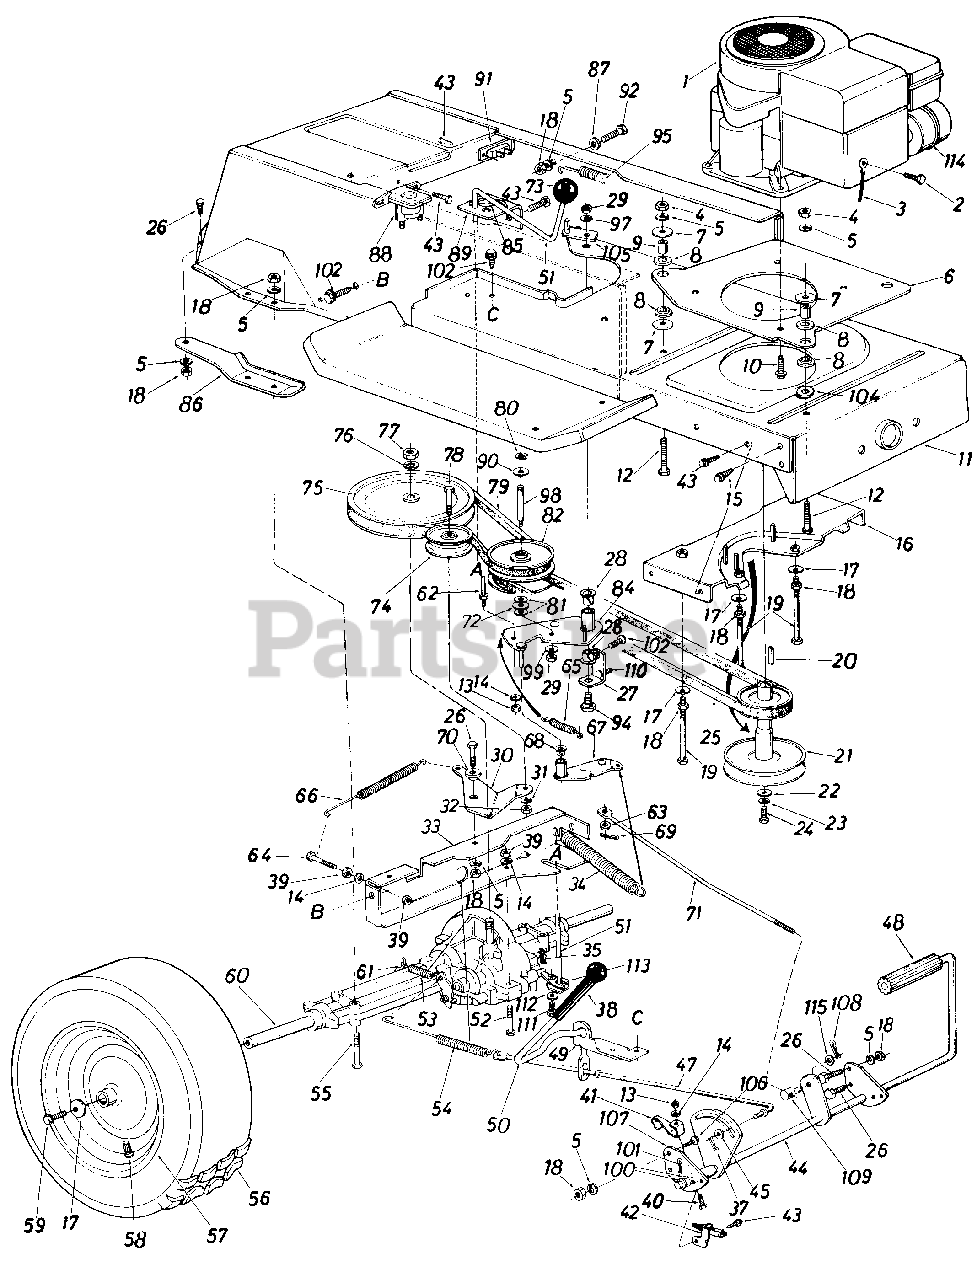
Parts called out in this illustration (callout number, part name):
1	Engine
2	Hex Bolt 1/4-20 x .62" Lg.
3	Electric Ground Wire
4	Hex Nut 5/16-24 Thd.
5	L-Wash. 5/16" I.D.
6	Engine Mounting Plate
7	Fl-Wash. .320" I.D. x 1.25"
8	Engine Mounting Grommet
9	Spacer
10	Hex Bolt 3/8-16 x 1.25" Lg.
11	Lower Frame Ass'y.
12	Hex Bolt 5/16-24 x 1.25"
13	Hex Nut 1/4-20 Thd.
14	L-Wash. 1/4" I.D.
15	Hex Wash. Hd. AB-Tap Scr. 5/16" x.75" Lg.
16	Belt Guard Brkt. Ass'y.
17	Bell-Wash. .345" I.D. x .88"
18	Hex Nut 5/16-18 Thd.
19	Hex Bolt 5/16-18 x 4" Lg.
20	Sq. Key 1/4" x 1/4" x 2.00"
21	Engine Pulley
22	Fl-Wash. 7116" I.D. x 1.25"
23	L-Wash. 7116" I.D.
24	Hex Bolt 7/16-20 x 1.50n Lg.
25	Variable Speed Belt
26	Hex Bolt 5/16-18 x .75" Lg.
27	Bearing Shaft Bracket Ass'y.
28	Flanged Nyliner Brg. 5/8n l.D. x .88" Lg.
29	Hex Nut 3/8-24 Thd.
30	Idler Bracket
31	L-Wash. 318" I.D.
32	Hex Nut 3/8-24 Thd.
33	Transaxle Support Brkt.
34	Ext. Spring .94" O.D. x 6.7
35	Inter. Cott-Pin
37	Cotter Pin 3132" Dia. x .75"
39	Hex Nut 1/4-28 Thd.
40	Hex Bolt 1/4-20 x 1.00" Lg.
41	Switch Actuator
42	Safety Switch
43	Hex Wash. Hd. S-Tap Scr. 1/4-20 x .50 Lg.
44	Clutch & Brake Pedal Ass'y.
45	Fl-Wash.
47	Brake Rod 20.9" Lg.
48	Foot Pad
49	Brake Lever Bracket
50	Hill Holder Brake Handle
51	Shift Lever Ass'y.
52	Hex Bolt 1/4-28 x 1.75" Lg.
53	Ext. Spring .38n O.D. x 2.5"
54	Ext. Spring .59n O.D. x 7 08"
55	Hex Bolt 5/16-18 x 2.75"
58	Air Valve
59	Hex Bolt 5/16-24 x .75" Lg.
60	Transaxle Complete
61	Brake Return Spring Anchor
62	Belt Guard Pin 1/4-20 Thd.
63	Fl-Wash. .34" I.D. x .68" O.D.
64	Hex Bolt 1/4-28 x 1.25" Lg.
65	Ext. Spring .50" Dia.
66	Ext. Spring .62" O.D. x 6.12"
67	Variable Speed Torque Brkt. Ass'y.
68	Flanged Bearing
69	Cotter Pin 3/32" Dia.
70	Shoulder Spacer 500n Dia. x.27" Lg.
71	Speed Control Link
72	Truss Bearing .56 Dia. x 1.25"
73	Knob
74	Fl-ldler Pulley 3.25" x 1.0"
75	1/2" "V"-Pulley 8.0" O.D. x .501 " I.D.
76	L-Wash. 1/2" I.D.
77	Hex Jam Nut 1/2-20 Thd.
78	Hex Bolt 3/8-24 x .75" Lg.
79	Variable Speed Belt
80	Snap Ring .56" Dia.
82	Variable Speed Pulley Ass'y. 5" O.D.
84	Variable Speed Brkt. Ass'y.
85	Comp. Spring-Clip
86	Transaxle Support Brkt.-R.H.
87	Fl-Wash. .34 I.D. x 1.12 O.D.
88	Solenoid
89	Shift Lever Bracket
90	Teflon Washer
91	Circuit Breaker
92	Hex Bolt 5/16-18 x 1.50" Lg.
94	Shld. Bolt 3/8-24 x 3.12" Lg.
95	Ext. Spring .99" O.D. x 11.0"
97	Bell-Wash. .38" I.D. x .88n
98	Shaft 56" Dia. x 3.875" Lg.
99	Bell-Wash. .39" I.D. x 1.12"
100	Fl-Wash.
101	Cotter Pin 3132n Dia. x 1.0"
102	Hex Wash. Hd. Scr. 5/16-18 0 x 62" Lg.
104	Fl-Wash. 32n l.D. x 1.25"
105	Belt Guard
106	Truss Mach. Scr. 5/16-18 x .75" Lg.
107	Pedal Bracket
108	Cotter Pin 3/32" Dia. x .75"
109	Ferrule
110	Hex Bolt 5/16-18 x 1" Lg. (Gr. 5)
111	Hex Bolt 1/4-28 x 50" Lg.
112	Bell-Wash. .265" I.D. x .75"
113	Shift Lever Link Ass'y.
114	Muffler
115	Fl-Wash. 385" l.D. x .62" O.D.
